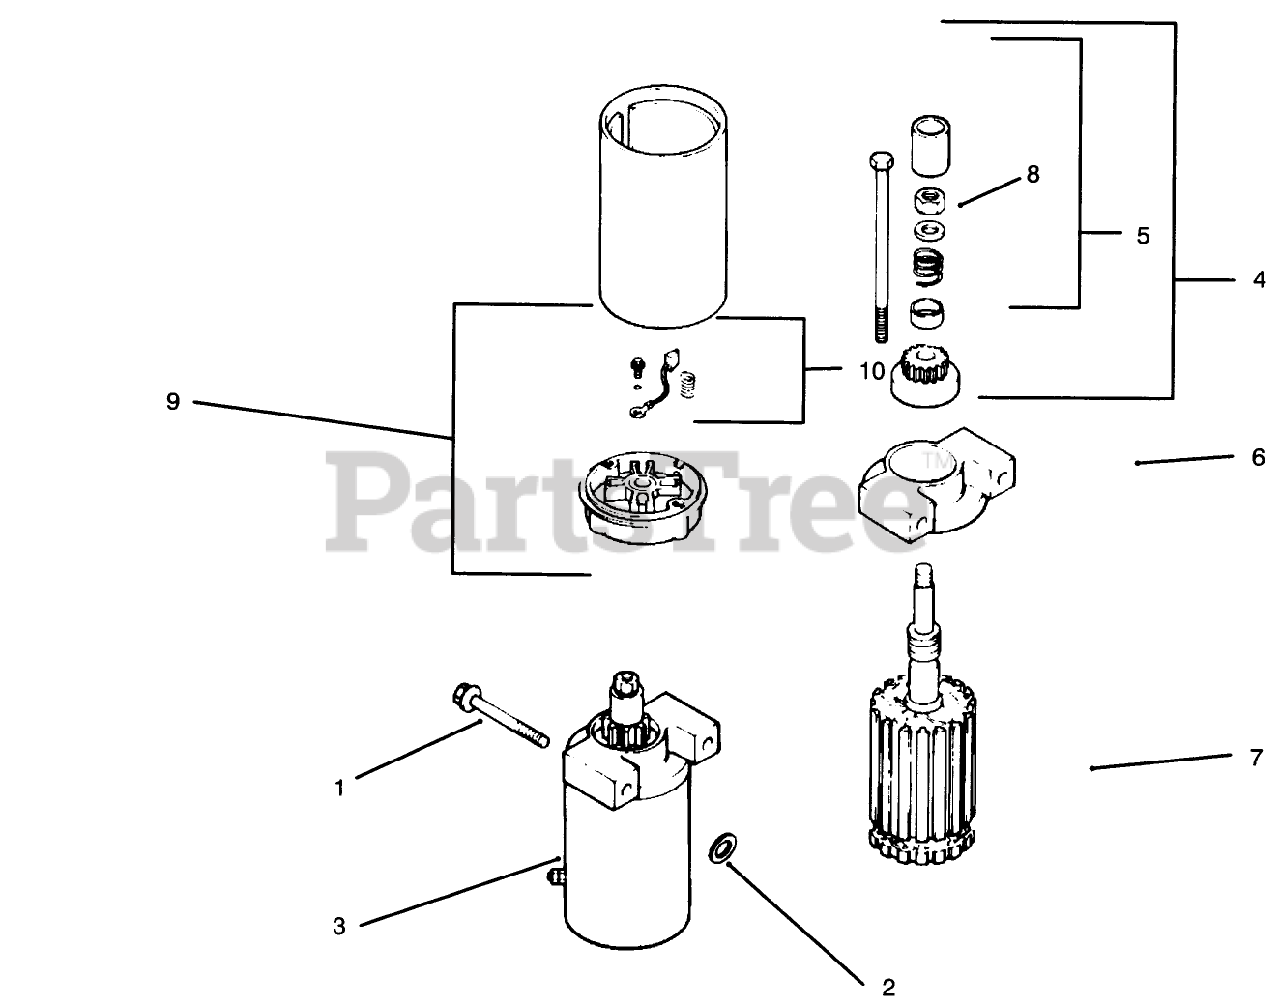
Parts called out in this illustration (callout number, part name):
2	Washer (Only On: 72042, 72063, 72062, 72043)
3	Starter (Incl. Ref. #4-10)
4	Kit-Drive INC 7 (Only On: 72042, 72063, 72062, 72043)
5	Kit-Drive Parts (Only On: 72042, 72063, 72062, 72043)
6	Cap-Drive End
7	Armature (Only On: 72042, 72063, 72062, 72043)
8	Screw-HF (Only On: 72042, 72063, 72062, 72043)
9	Cap-Commutator End
10	Kit-Brush
